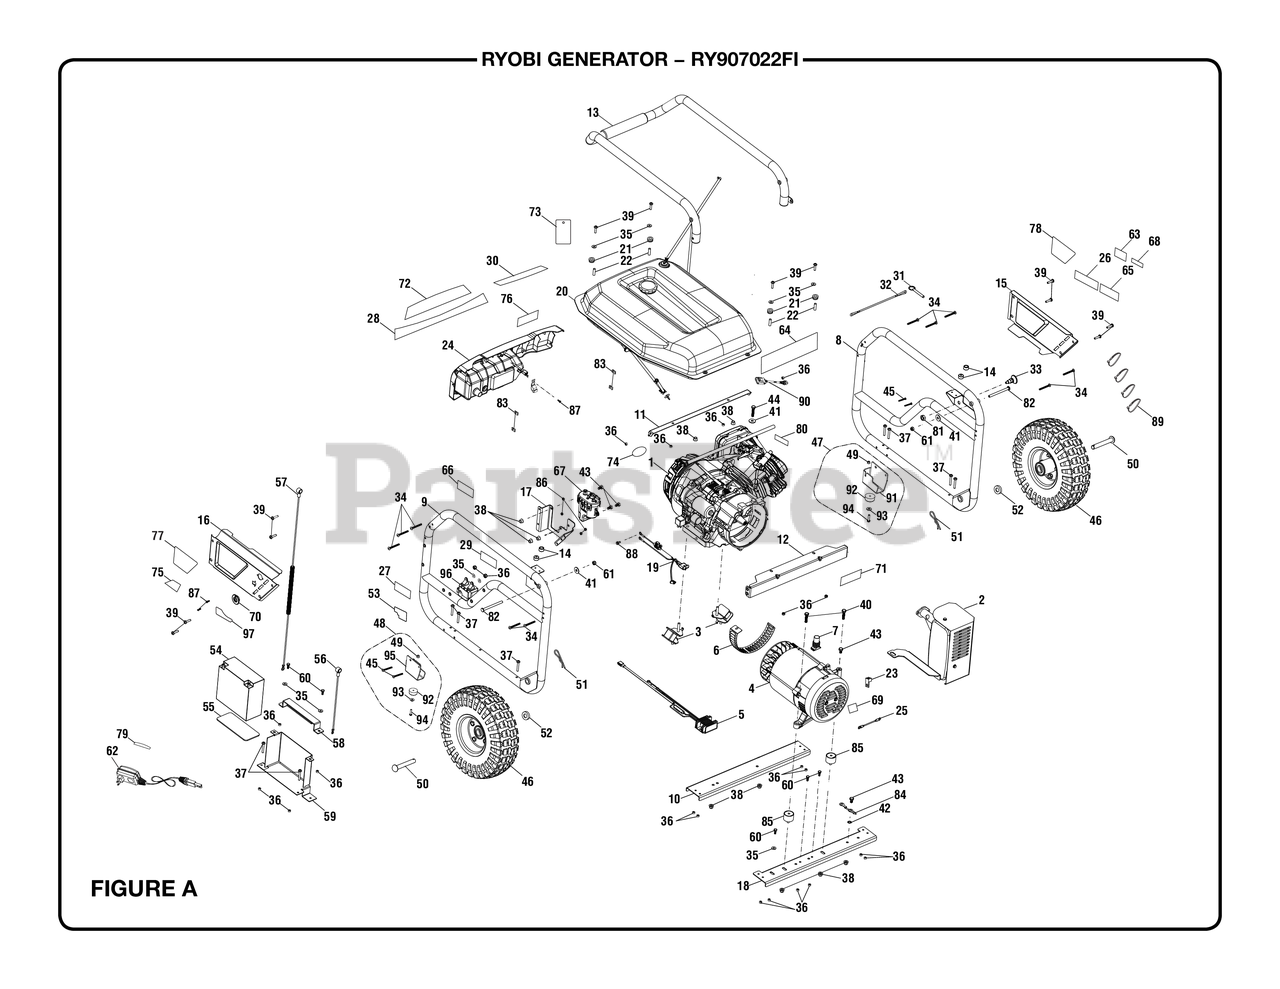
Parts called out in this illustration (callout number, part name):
1	Engine (R420 EFI)
2	Muffler Assembly
3	Vibration Isolator
4	Generator Head Assembly (See Figure B)
5	Ac To Dc Regulator
6	Fan Cover (Generator Head)
7	Rubber Boot
8	Frame Assembly (Left)
9	Frame Assembly (Right)
10	Cross Member
11	Fuel Tank Support (Front)
12	Fuel Tank Support (Rear)
13	Handle Assembly
14	Rubber Bumper
15	Panel (Left)
16	Panel (Right)
17	Fuel Pump Mounting Bracket
18	Cross Member
19	Battery Storage Charger Wire Harness
20	Fuel System
21	Bushing (Fuel Tank Isolator)
22	Spacer (Fuel Tank Isolator)
23	Ground Lug (1/4-20)
24	Electrical Panel
25	Bonding Wire
26	Hot Surface Label (Trilingual)
27	Engine Lubricant Label
28	Performance Label
29	Lock Pin Label
30	Quick Start Label
31	Release Pin (5/16 x 2 in.)
32	Lanyard (3/16 in.)
33	Handle Lock Assembly
34	Screw (M6 x 50 mm, T30 Torx Pan Hd. )
35	Washer (OD17 x ID6.4 x 1.6t)
36	Lock Nut (M6 x 1 mm)
37	Bolt (M6 x 42 mm, T30 Torx Hex Hd.)..
38	Flange Lock Nut (M8 x 1.25 mm)
39	Bolt (M6 x 25 mm,T30 Torx Pan Hd.)
40	Bolt (M8 x 1.25 in., Hex Hd.)
41	Washer (ID9 x OD25.4 x 2t)
42	Star Washer (M8)
43	Bolt (M8 x 15 mm, Hex Hd.)
44	Screw (M8 x 40 mm, Hex Hd.)
45	Bolt (M6 x 48 mm, Button Hd.)
47	Foot (Left)
48	Foot (right)
49	Lock Nut (5/16-18, Hex Hd.)
51	Hitch Pin (M3)
52	Washer (5/8 in.)
53	CO Monitor LED Label
55	Gasket (Battery Hold Down Bracket)
56	Battery Cable (Red)
57	Battery Cable (Black 390 mm)
58	Battery Hold Down Bracket
59	Battery Tray
60	Screw (M6 x 16 mm, Hex Hd.)
61	Lock Nut (5/16-18, Hex Hd.)
62	Battery Charger
63	Inquires Label (Ryobi)
64	UL Fire Warning Label Spark Arrestor)
65	Fire Distance Label (Eng/Sp)
66	Risk of Fire Danger Label
67	Returnless Fuel Pump
68	Quick Release Pin Label
69	Ground Label Icon
70	Fuel Valve Bezel
71	Ground Warning Label
72	Logo Label
73	Warning Hangtag
74	Engine Recoil Label
75	Charge Cable Label
76	EFI Logo Label (Front)
77	CO Automatic Shutdown Label
78	EFI Logo Label (Left)
79	Battery Maintainer Label
80	Throttle Body EFI Logo Label
81	Lock Nut (1/2-20, Hex)
82	Pivot Pin, Handle 5/16-18 x 3.875 in.)
83	U-Clip (M6)
84	Assembly, ground wire
85	Isolator Generation 7
86	Lock Nut (M5)
87	Screw (M4 x 12 mm, T20 Torx Pan Hd.)
88	Bolt (M5 x 10 mm, Flange Hex Hd.)
89	Cable Tie
90	O2 Sensor
91	Foot Tall Bracket (Left)
92	Rubber Wear Pad
93	Washer (1/4 in.)
94	Bolt (M6 x 20 mm, Hex Hd.)
95	Foot Tall Bracket (Right)
96	CO Detector
97	Fuel Valve Label
